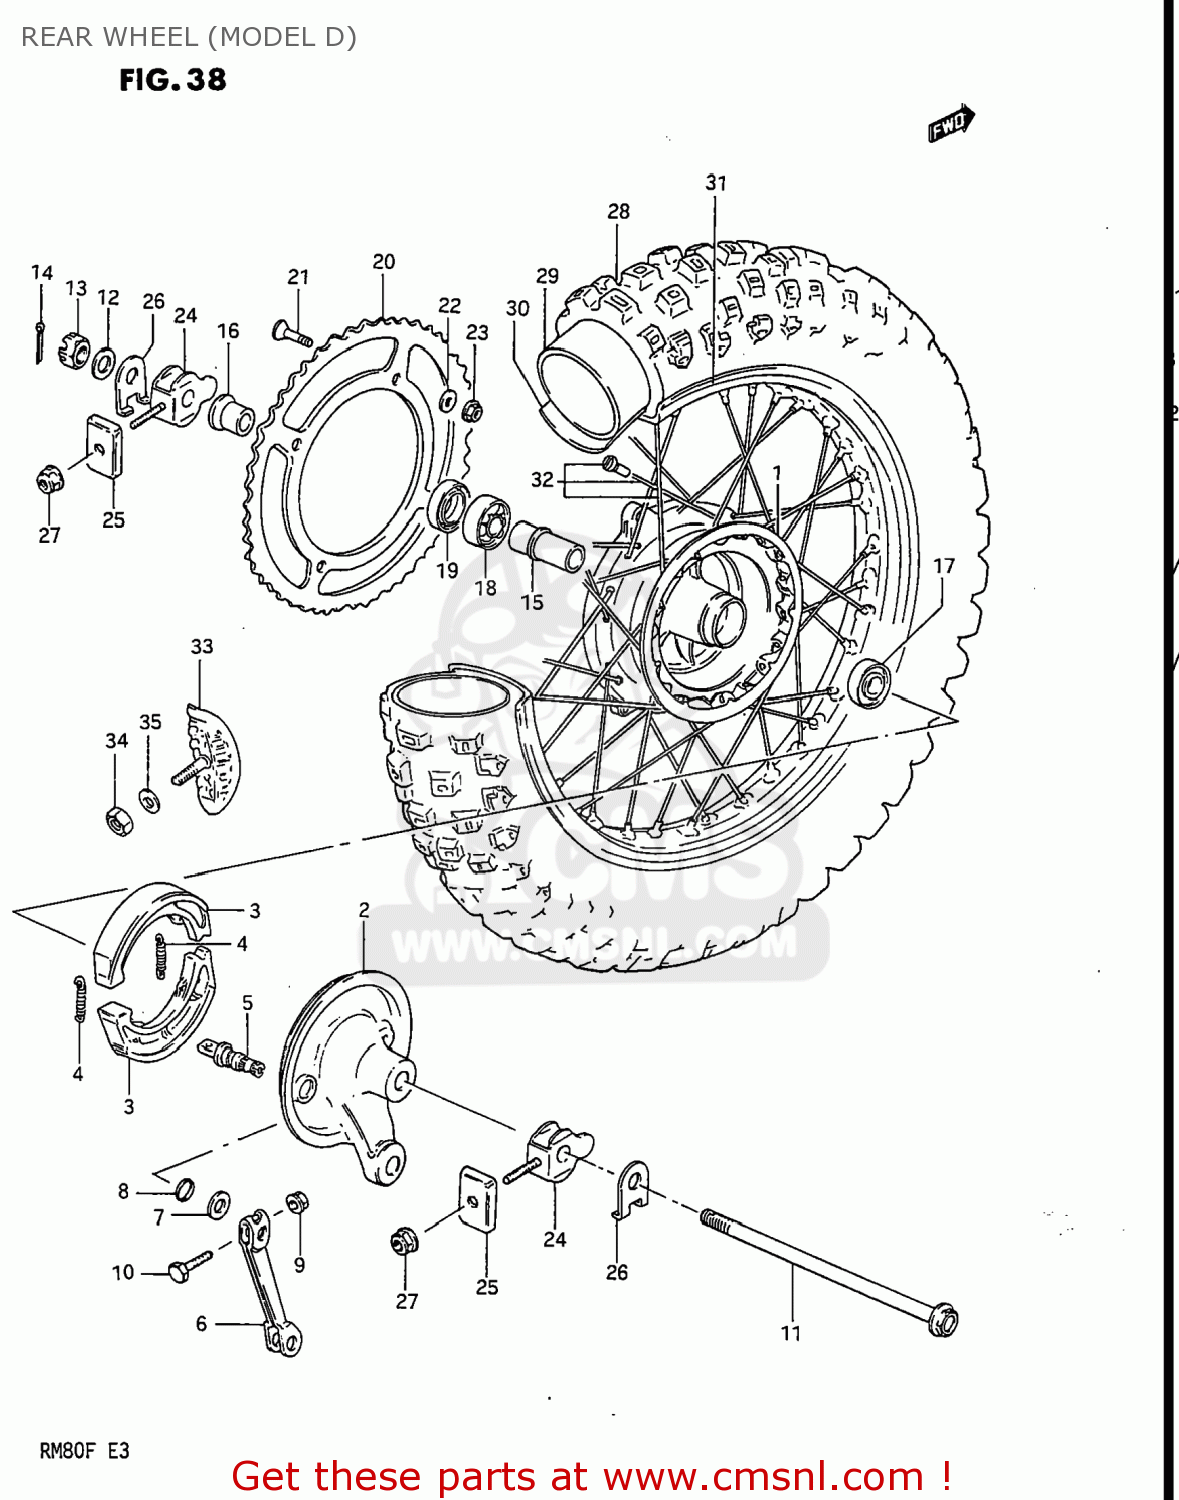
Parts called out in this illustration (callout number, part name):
1	HUB,REAR
2	PANEL,REAR HUB
3	SHOE,BRAKE
4	SPRING(L:35.8)
5	CAM,BRAKE
6	LEVER,RR BRAKE CAM
7	WASHER(12.5X20X1)
8	O RING(D:2.5,ID:11.4)
9	NUT
10	BOLT
11	AXLE,REAR
12	WASHER
13	NUT 12MM
14	PIN 30X20
15	SPACER,REAR HUB BEARING
16	SPACER,RR AXLE,L
17	BEARING, RH
18	BEARING
19	OIL SEAL(17X38X5)
20	SPROCKET,REAR
21	SCREW(8X33.5)
22	WASHER
23	NUT
24	ADJUSTER CHAIN
25	ADJUSTER,CHAIN
26	WASHER,CHAIN ADJUSTER
27	NUT
28	TIRE
29	TUBE ASSEMBLY,WHEEL,INNER
30	PROTECTOR,INNER TUBE
31	RIM,REAR WHEEL
32	SPOKE SET
33	STOPPER,BEAD
34	NUT
35	WASHER
